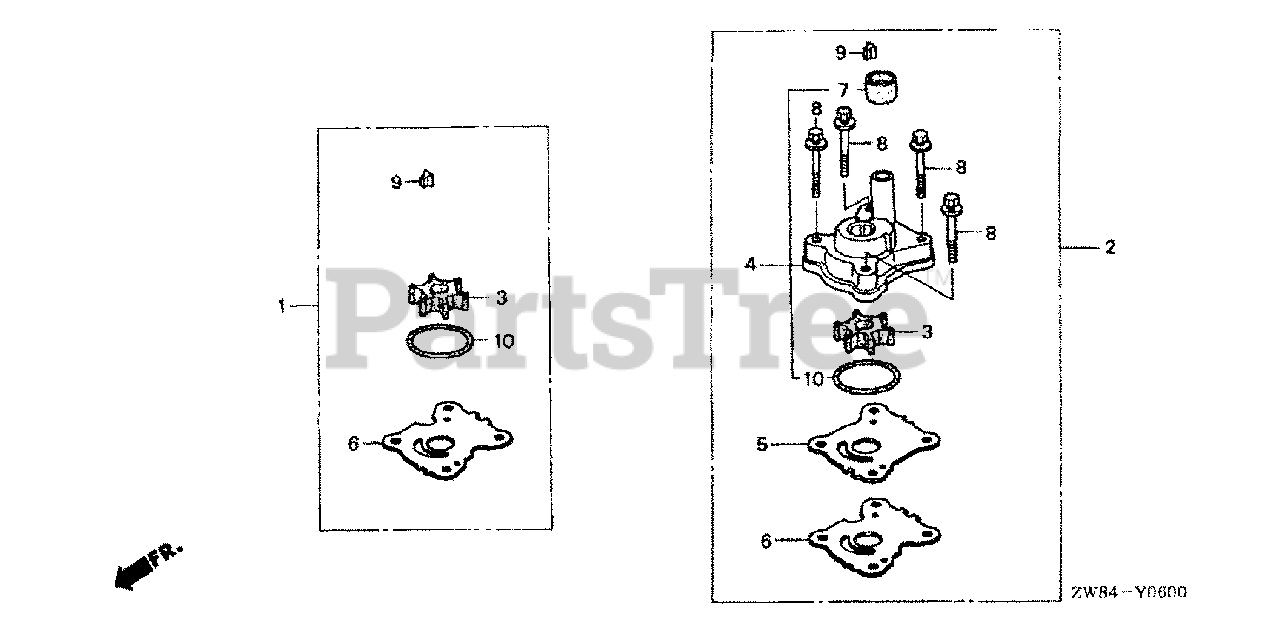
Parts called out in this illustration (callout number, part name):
1	PUMP KIT, IMPELLER
2	PUMP KIT, IMPELLER
3	IMPELLER, PUMP (S,L)
4	HOUSING ASSY., IMPELLER
5	COVER, IMPELLER
6	GASKET, IMPELLER
7	RING, WATER TUBE SEAL
8	BOLT-WASHER (6X50)
9	KEY, WOODRUFF
10	O-RING (42.2X2.4)
